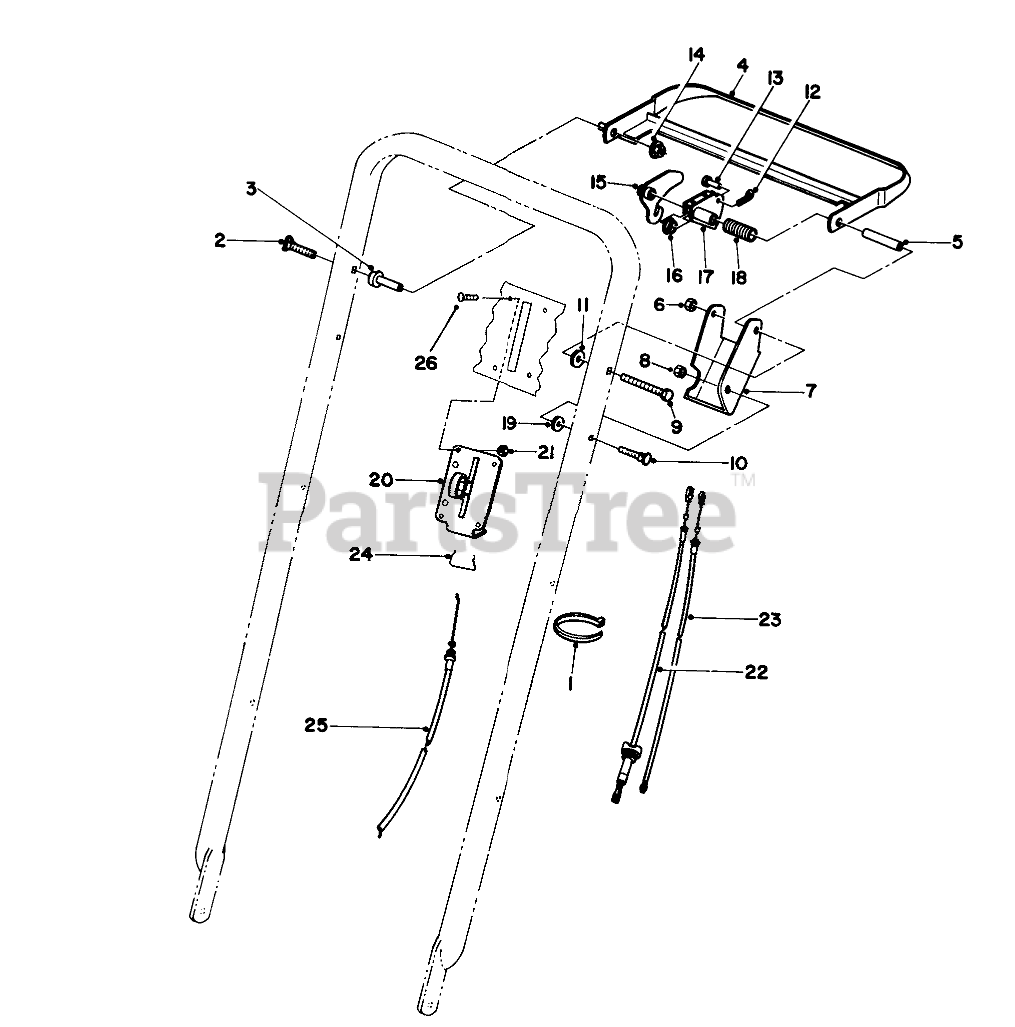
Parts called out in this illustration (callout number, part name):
1	TIE-CABLE
2	SCREW
3	SPACER-SUPPORT
4	Bar-Control
5	SPACER-BRACKET, CONTROL
6	NUT-LOCK, NI
7	Bracket-Control
8	NUT-LOCK, NI
9	SCREW-HH
10	SCREW-HANDLE
11	SPACER
12	PIN-COTTER
13	PIN-CABLE
14	NUT-LOCK, NI
15	LEVER-TRACTION
16	BUSHING-FLANGE
17	LEVER-BBC
18	SPRING-CONTROL
19	SPACER
20	CONTROL-THROTTLE
21	NUT-LOCK, NI
22	CABLE-TRACTION
23	CABLE-CLUTCH
24	RETAINER-CABLE, THROTTLE
25	CABLE-THROTTLE
26	SCREW-PPH
